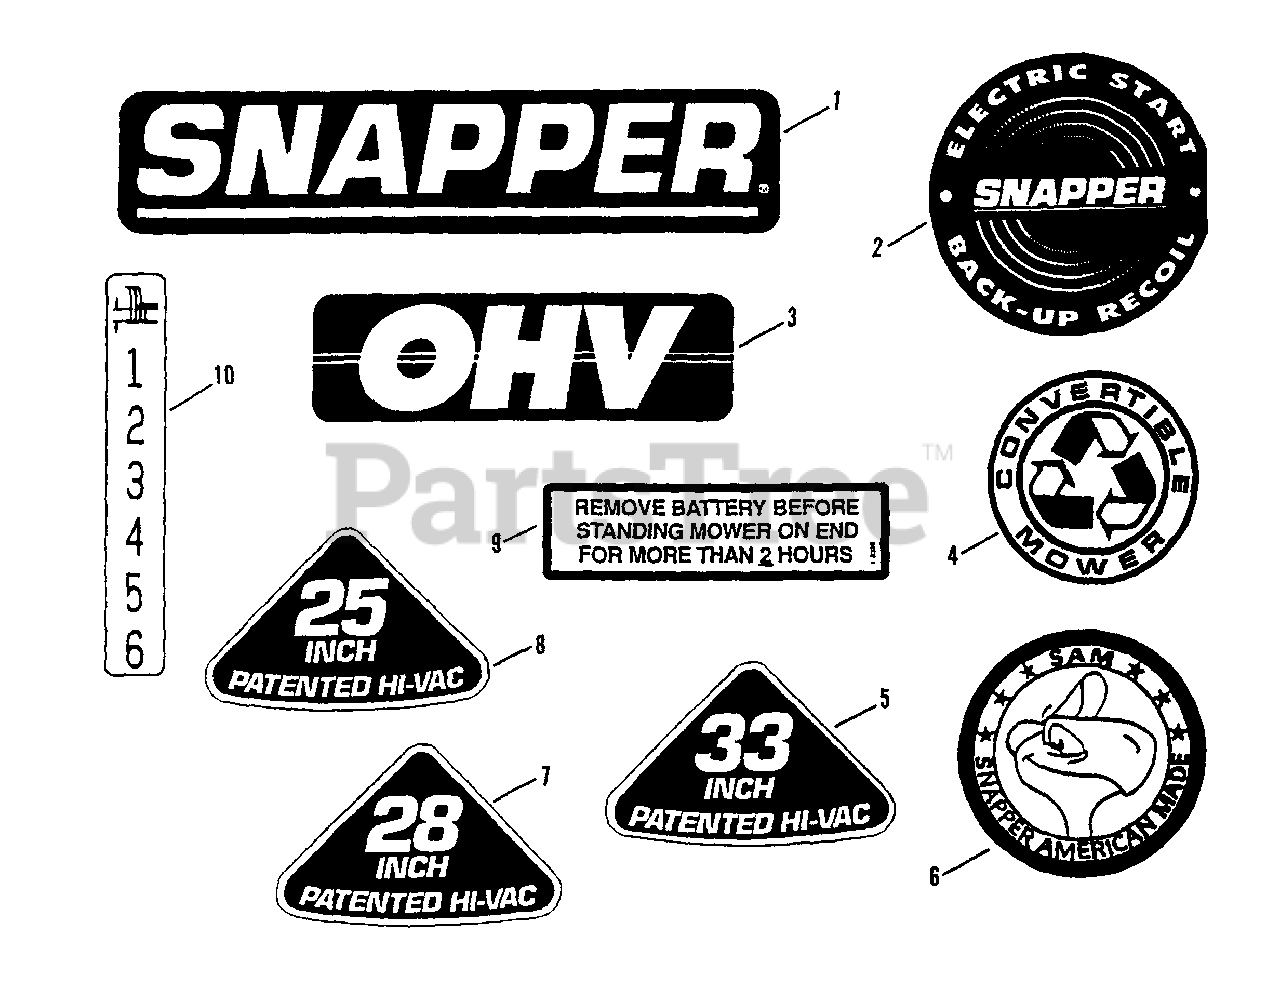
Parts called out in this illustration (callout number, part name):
1	DECAL, SNAPPER (Molded Logo)
2	DECAL, Back-Up Recoil
3	DECAL, OHV
4	LOGO, Convertible (Silver)
5	DECAL, 33 Inch
6	MEDALLION, "Sam"
7	DECAL, 28 Inch
8	DECAL, 25 Inch
9	DECAL, Battery
10	DECAL, Height Of Cut
